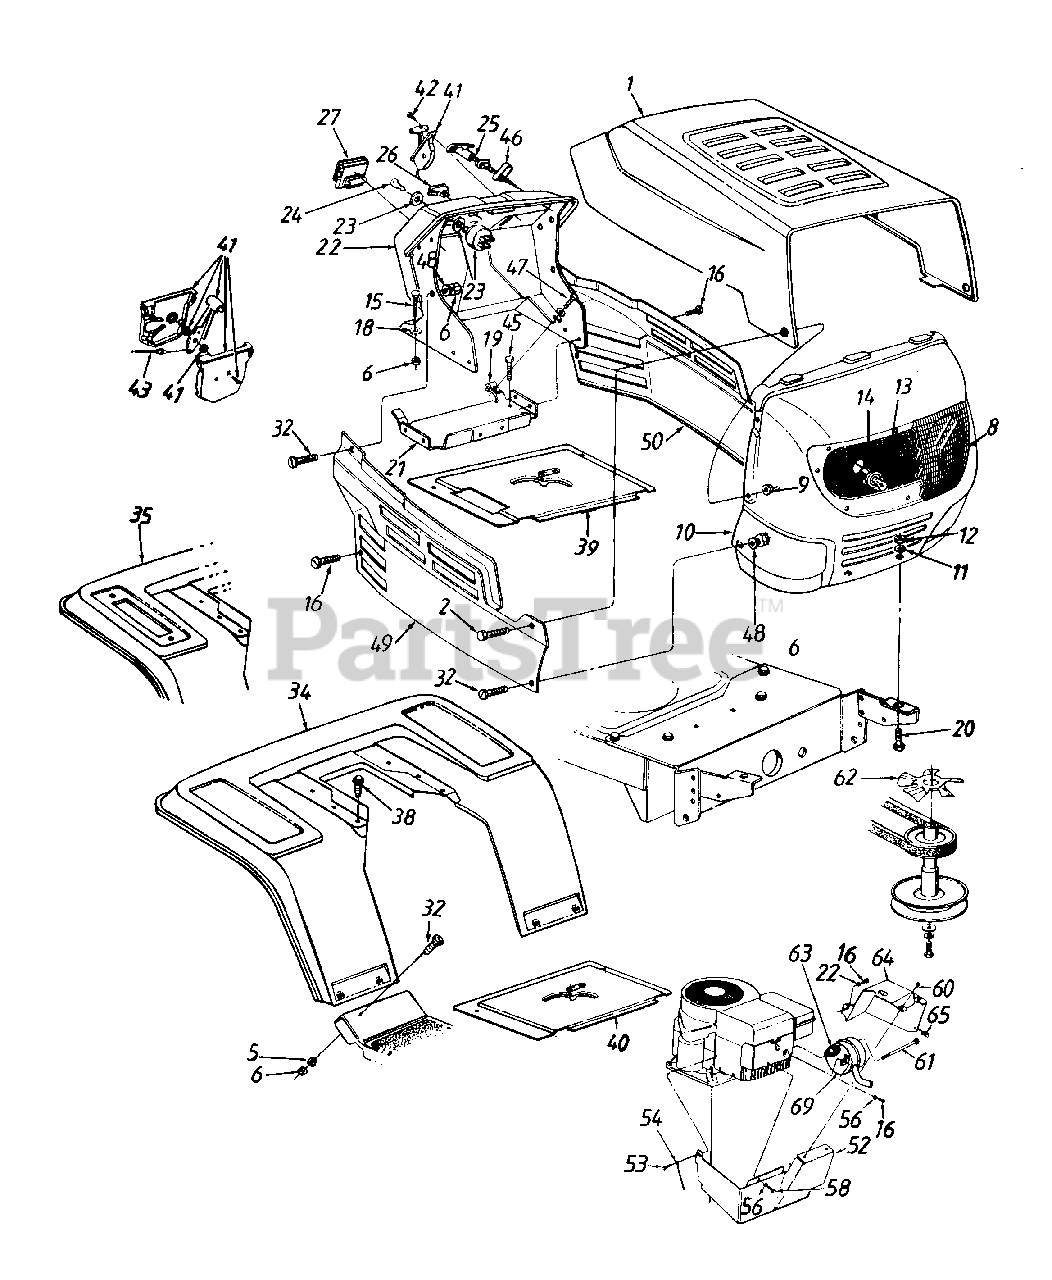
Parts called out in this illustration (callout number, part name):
6	Hex Nut 1/4-20 Thd.
9	Flange L-Nut 1/4-28 Thd.
11	Fl-Wash. .344" I.D. x 1" O.D.
12	Hex Nut 5/16-18 Thd.
13	Lamp
14	Socket
15	Carriage Bolt 1/4-20 x .75" Lg.
16	Hex Wash. Hd. TT-Tap Scr. 1/4-20 x .5" Lg.
17	Fl-Wash. .281" I.D. x .73" O.D.
18	Bolt Retainer 1/4" I.D.
19	Speed Nut 1/4-20 Thd.
20	Hex Bolt 5/16-18 x .75" Lg.
23	Ignition Switch
24	Ignition Key
25	Choke Control
26	Light Switch
27	Ammeter
32	Truss Mach. Scr. 1/4-20 x .5" Lg.
41	Throttle Box Ass'y.
42	Truss Mach. AB-Tap Scr. #10 x .5" Lg.
43	Throttle Control Wire
45	Hex Wash. Hd. B-Tap Scr. 5/16-18 x .5" Lg.
46	Choke Retainer
47	Hex TT-Tap Scr. 1/4-20 x .75" Lg.
48	Bell-Wash. .265" I.D. x .75"
49	Lens
53	Truss Mach. Scr. 5/16-18 x .75" Lg.
54	Ground Wire
56	Spr. Wash. 1/4" I.D.
58	Hex Bolt 1/4-20 x 3/8" Lg.
60	Hex B-Tap Scr. #10 x .38" Lg.
61	Shoulder Bolt
63	Exhaust Gasket
69	Muffler
70	L-Wash. 1/4" I.D.
17870-0498	FENDER-RR W/FRAME - OLD CUB YELLOW (0498)
17870-0638	FENDER-RR W/FRAME - MTD/TROY-BILT RED (0638)
17870-0667	FENDER-RR W/FRAME - MIDNIGHT BLUE (0667)
